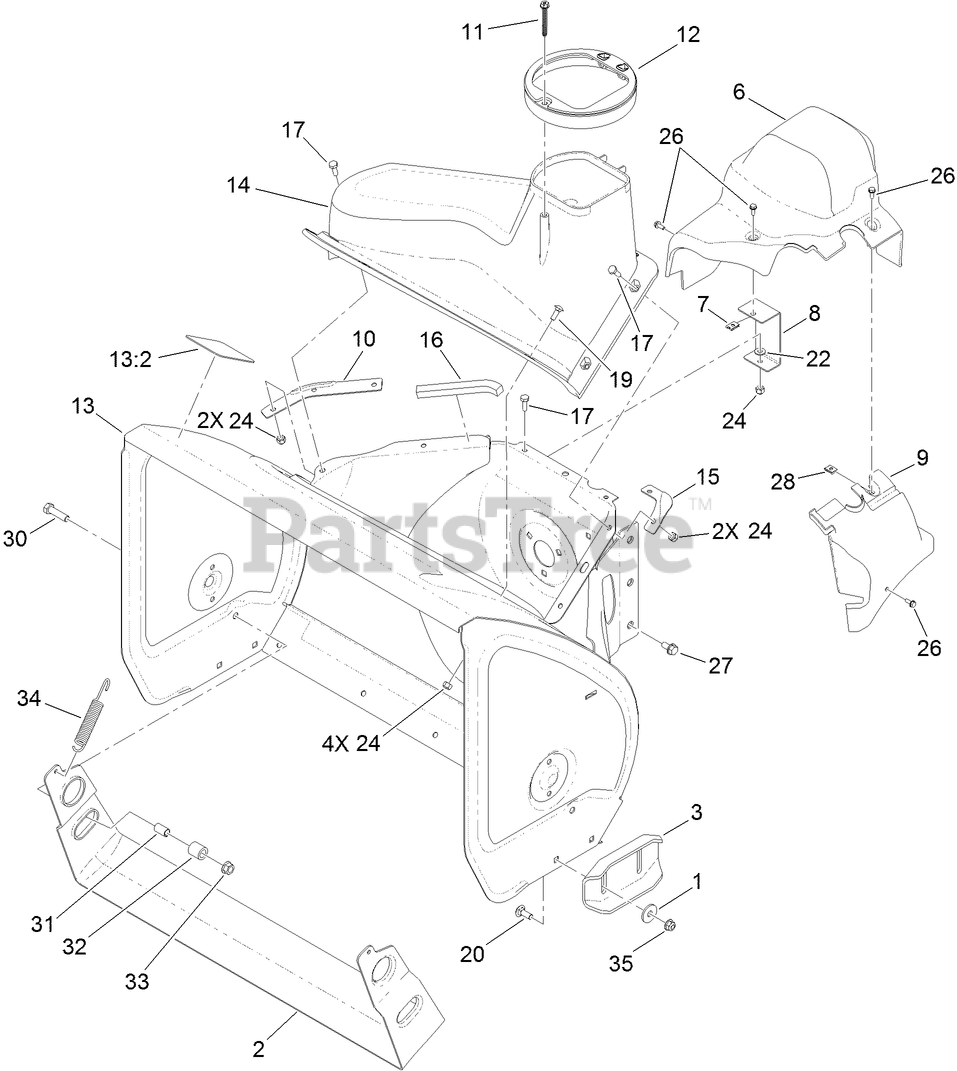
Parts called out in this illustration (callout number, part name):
1	WASHER
2	SCRAPER-PIVOTING, 28 INCH
3	SKID-CAST
6	COVER-BELT
7	NUT-SPEED
8	BRACKET-COVER, CLIP NUT
9	COVER-EXTENSION, BELT
10	SEAL-FLANGE, COVER
11	SCREW-HWH, PLASTITE
12	GUIDE-CHUTE
13	HOUSING-AUGER, 28 INCH
13:2	DECAL-DANGER
16	SEAL-HOUSING
17	SCREW-HH
19	BOLT-CARR
20	SCREW-CARR
22	WASHER-FLAT
24	NUT-LOCK, NI
26	SCREW-HWH
27	SCREW-HWHTF
28	NUT-SPEED
30	SCREW-HH
31	SPACER-SCRAPER, STOP
32	CUSHION-SCRAPER, STOP
33	NUT-HF
34	SPRING-SCRAPER
35	NUT-HF, NI
